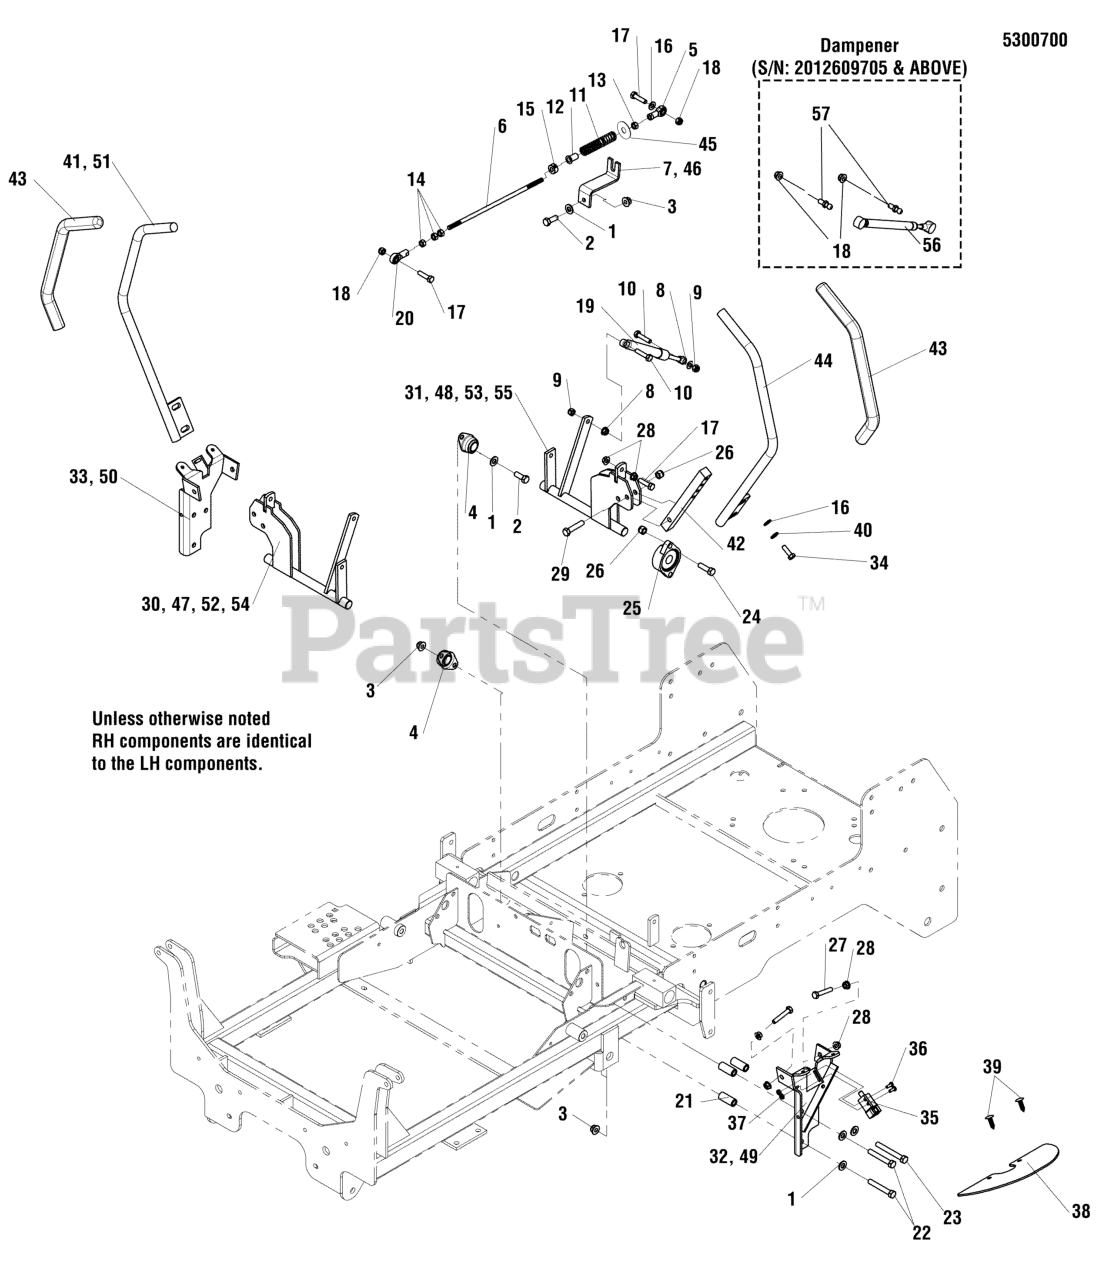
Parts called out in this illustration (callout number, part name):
1	WASHER, 3/8 SAE
2	BOLT, 3/8-16 X 1" GD5 CZ
3	NUT, 3/8-16 HEX NYLOCK FLANGE
4	BEARING, BRONZE FLANGE, 3/4
5	BALL JOINT 5/16-24 LH FEMALE BRONZE RACE
6	ROD, HYDRO LINKAGE
7	MOUNT, REVERSE RETURN - BLK
8	NUT, M8-1.25 SERR. FLANGE, CZ
9	NUT, M8-1.25 NYLON LOCK, CZ
10	BOLT, M8-1.25 X 35MM, GD8.8
11	SPRING, REVERSE RETURN
12	BUSHING, NYLON
13	NUT, 5/16-24 HEX, LH
14	NUT, 5/16-24 HEX
15	COLLAR, 5/16" SET
16	WASHER, 5/16" SAE
17	BOLT, 5/16-18 X 1-1/4" GD5 YZ
18	NUT, 5/16-18 HEX NYLOCK FLANGE
19	DAMPENER, CONTROL
20	BALL JOINT 5/16-24 RH FEMALE BRONZE RACE
21	SPACER, .39 X .63 X 1.50
22	BOLT, 3/8-16 X 2-1/2" GD5 CZ
23	BOLT, 3/8-16 X 3" GD5 CZ
24	BOLT, 3/8-16 X 1-1/4" GD5 CZ
25	BEARING, FLANGE
26	NUT, 3/8-16 HEX NYLON LOCK
27	BOLT, 5/16-18 X 1-3/4" GD5 TFL
28	NUT, 5/16-18 HEX SERRATED FLANGE (LARGE)
29	BOLT, 3/8-16 X 1-3/4" GD5 CZ
30	WELD, CONTROL SHAFT - RH - RED MODEL
31	WELD, CONTROL SHAFT - LH - RED MODEL
32	WELD, NEUTRAL LOCK, LH - BLK
33	WELD, NEUTRAL LOCK, RH - BLK
34	BOLT, 5/16-18 X 1" GD5 YZ
35	SWITCH, PLUNGER, N.O.
36	SCREW, #10-24 X 1/2" ROUND PHILLIPS
37	NUT, #10-24 HEX
38	GUARD, RUBBER MOTION CONTROL
39	PUSH RIVET (TREE TYPE), BLACK
40	WASHER, 5/16 LOCK CZ
41	WELD, HANDLE MOTION CONTROL RH - BLK
42	MOUNT, CONTROL ARM - BLK
43	GRIP, FOAM, 3/4" ID, 16" LONG
44	WELD, HANDLE MOTION CONTROL LH - BLK
45	WASHER, 3/8 X 1" X 1/16, NYLON F/W
46	MOUNT, REVERSE RETURN - BLK
47	WELD, CONTROL SHAFT - RH - ORANGE MODEL
48	WELD, CONTROL SHAFT - LH - ORANGE MODEL
49	WELD, NEUTRAL LOCK, LH - BLK
50	WELD, NEUTRAL LOCK, RH - BLK
51	WELD, HANDLE MOTION CONTROL RH - BLK
52	SHAFT, Control
53	WELD, CONTROL SHAFT, LH - BLK
54	SHAFT, Control
55	WELD, CONTROL SHAFT, LH - BLK
56	DAMPENER, CONTROL
57	10MM BALL STUD, 5/16-18 X 3/4"
